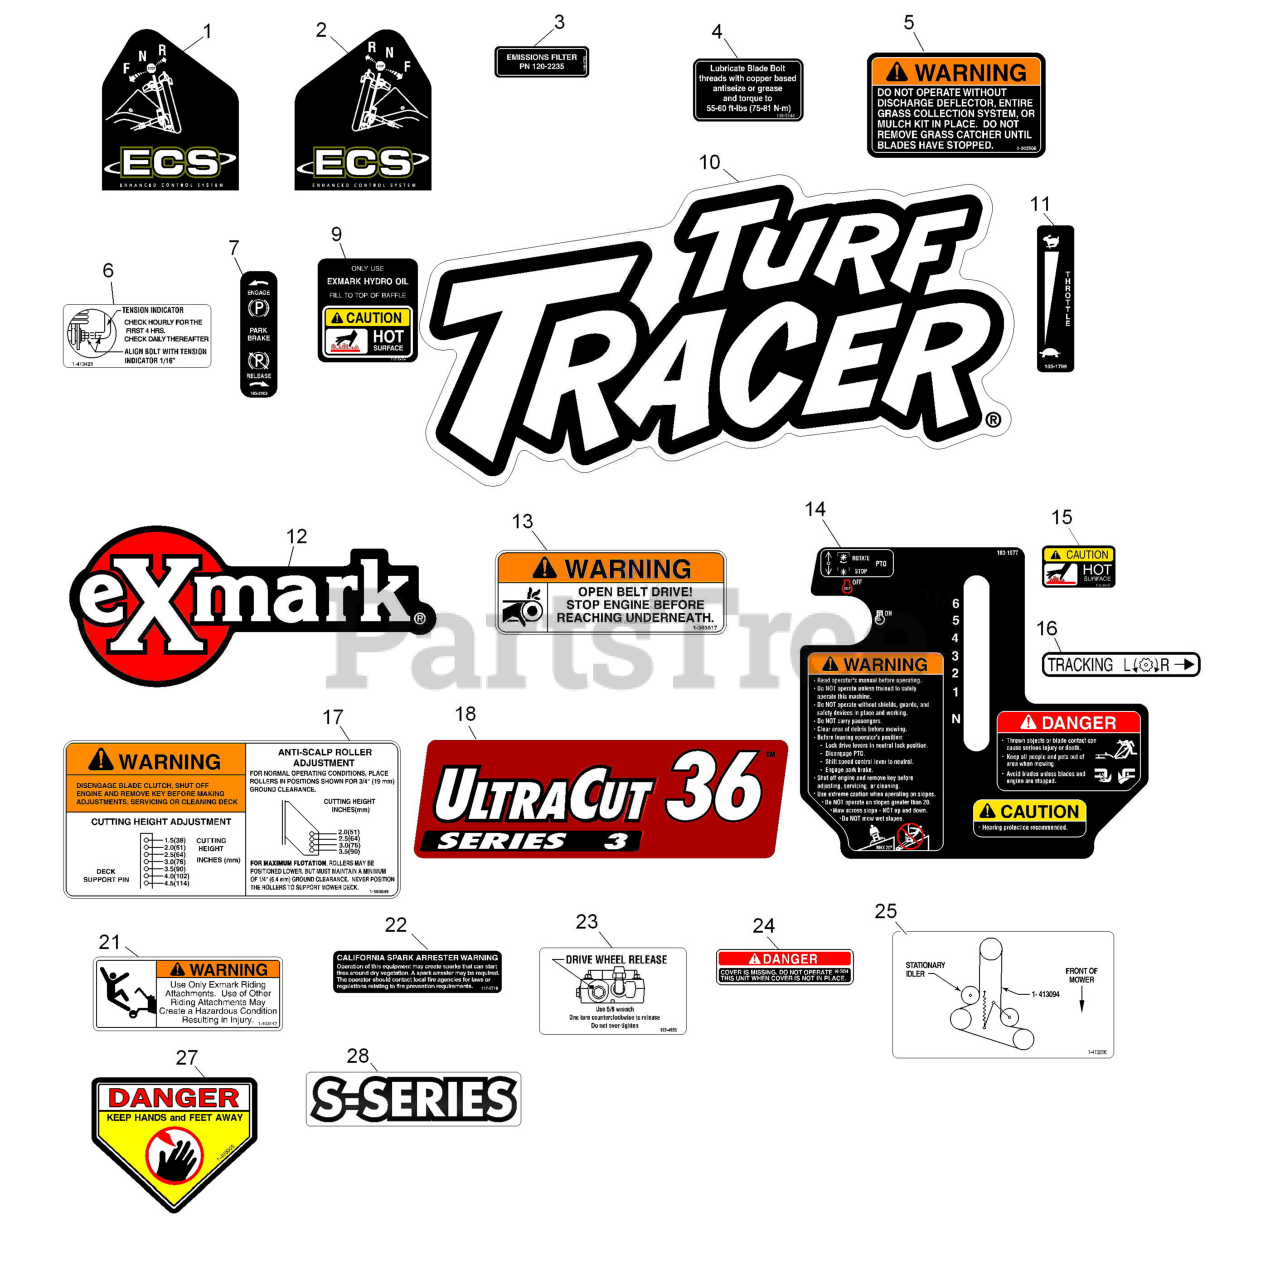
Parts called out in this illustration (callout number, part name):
1	DECAL,LH ECS INSTRUCTION
2	DECAL,RH ECS INSTRUCTION
3	DECAL-FILTER, EMISSIONS
4	DECAL,BOLT TORQUE
5	DECAL-WARNING, DISCHARGE
6	DECAL,INDICATOR
7	DECAL-BRAKE, PARK
9	DECAL-HYDRAULIC TANK
10	DECAL,TTH MODEL
11	DECAL,THROTTLE ONLY
12	DECAL,EXMARK LOGO
13	DECAL,BELT DRIVE
14	DECAL,ECS CONSOLE
15	DECAL-CAUTION
16	DECAL,TRACKING ADJUST
17	DECAL,ANTI SCALP
18	DECAL-ULTRACUT 36 SERIES
21	DECAL,SULKY WARNING
22	DECAL-ARRESTER, SPARK
23	DECAL,DRIVE RELEASE
24	DECAL-COVER, MISSING
25	DECAL,BELT ROUTING
27	DECAL-DANGER
28	DECAL-S-SERIES
